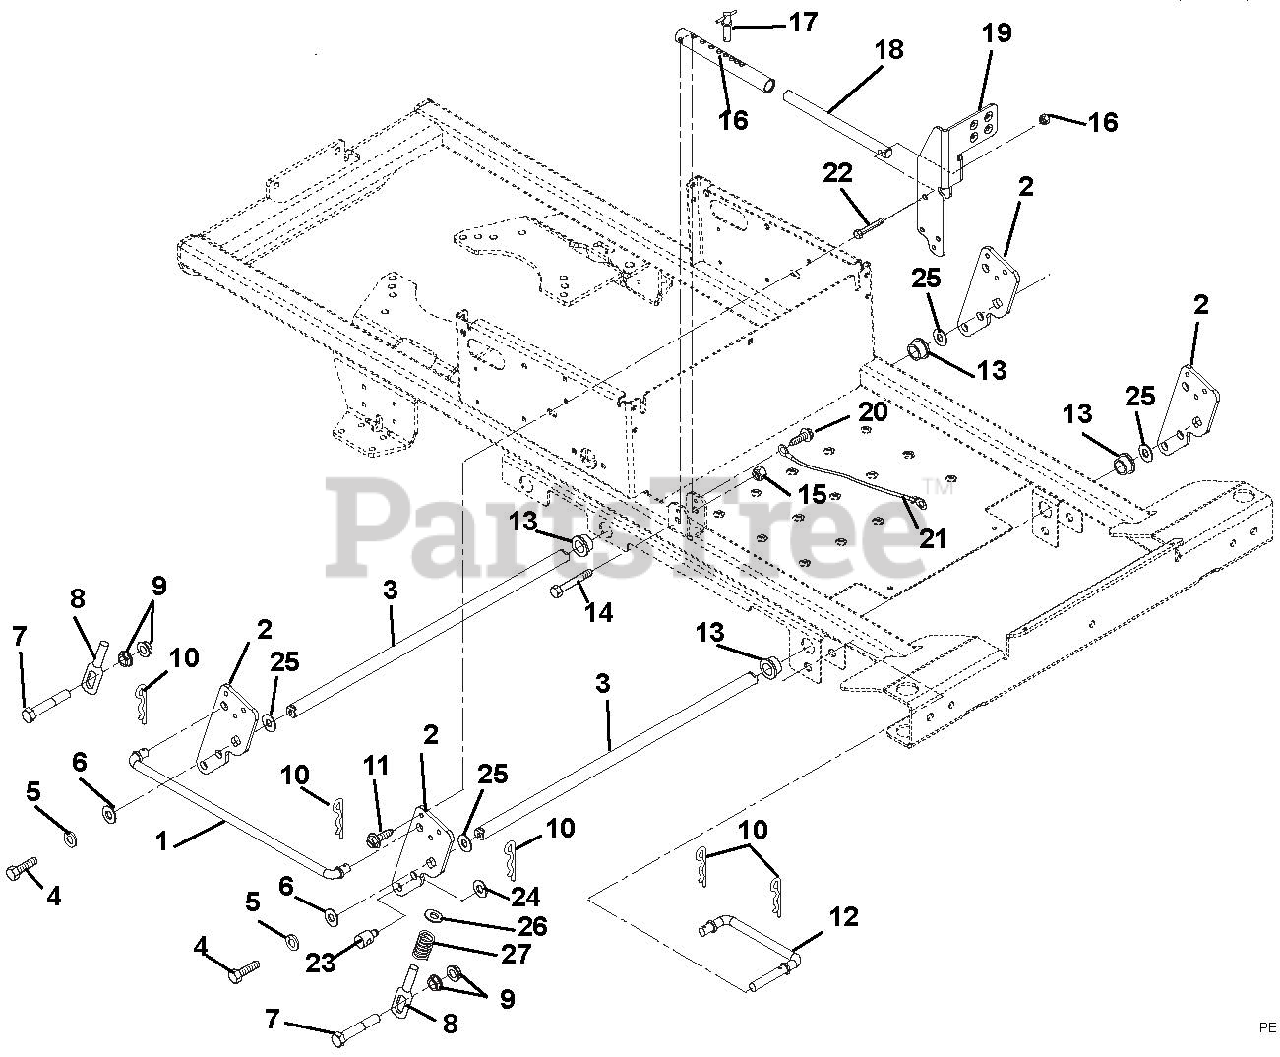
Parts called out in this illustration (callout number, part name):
1	ROD,LIFT
2	LIFT ARM
3	SHAFT,LIFT
4	@BLT-HEX .31-18X1.00 GR5 YWZC
5	WSHR-FL-STL .328X.87X.179 YWZC
6	WSHR-FL-STL .344X1.125X.135
7	@BLT-HEX .50-13X3.00 GR5 YWZC
8	DECK LINK
9	NUT-SPNLK-FLG .50-13 YWZC
10	PIN, HAIR, EXT - #16 YWZC
11	@SCR-TAP .31-18X.50 HWH TR YWZ
12	LINK,DRAG
13	BSHG-FLG .750X1.000X.625X1.250
14	@BLT-HEX .38-16X2.00 GR5 YWZC
15	@NUT-LK-NYL-FLG .38-16 YWZC
16	TUBE,LIFT STOP
17	PIN, SPRING BALL .375OD X 1.50
18	ROD,LIFT
19	PEDAL,FOOT LIFT
20	@SCR-TAP .25-20X.50 HWH TR YWZ
21	CBL,HOOD
22	@BLT-HEX .38-16X2.50 GR5 YWZC
23	TRUNNION-.50
24	WSHR-FL-STL.511X1.441X.125 YWZ
25	WSHR-FL-STL.755X1.375X.062YWZC
26	WSHR-FL-STL .515X1.625X.250 YZ
27	SG-COMP .105X1.35X2.00
